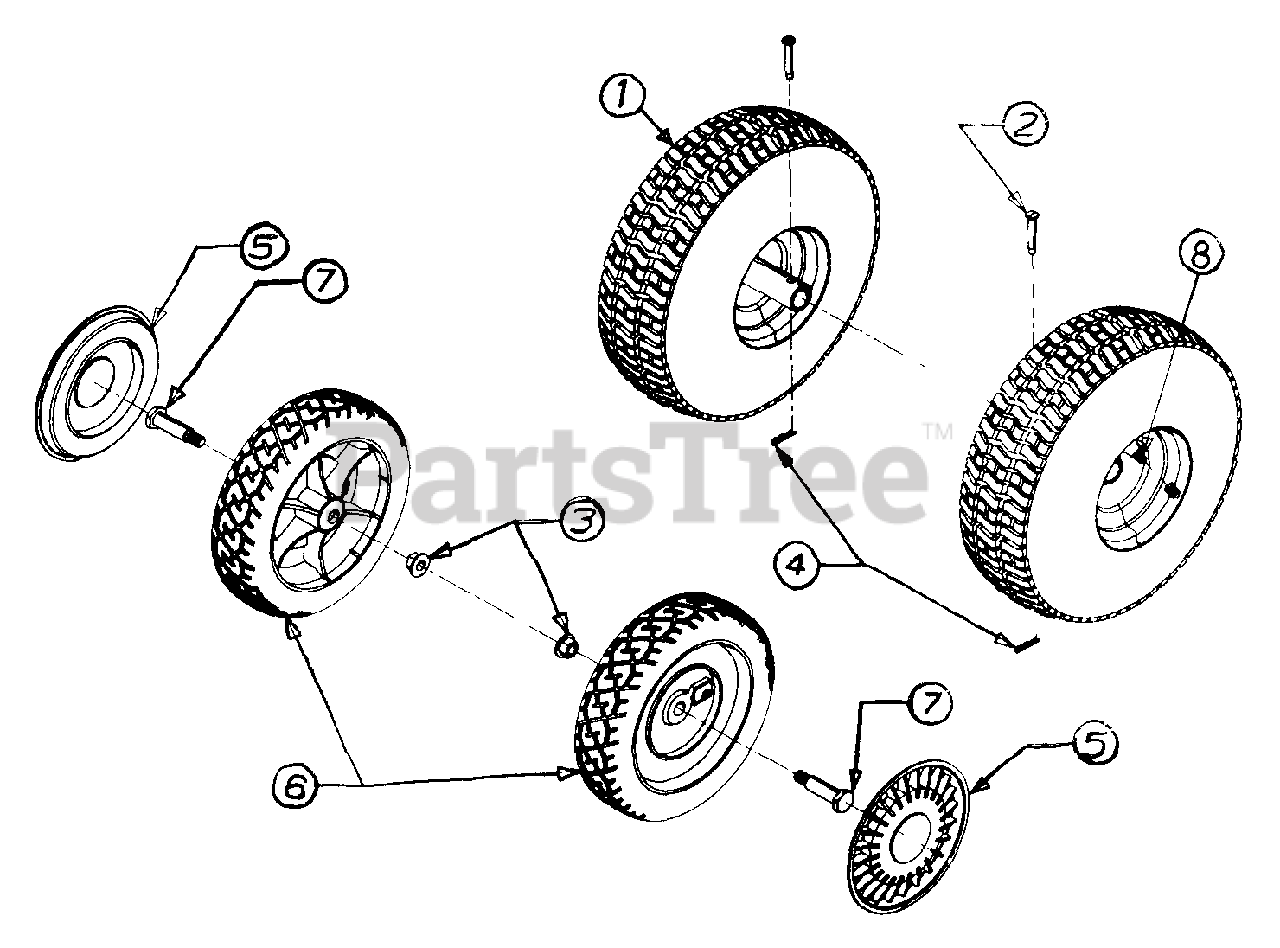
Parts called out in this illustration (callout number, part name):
1	WHEEL ASSY COMPLETE 4" X 10"
2	PIN - CLEVIS
3	NUT - HEX FLANGE
4	PIN - COTTER
5	HUB CAP
6	WHEEL 2" X 8"
7	SCREW - SHOULDER
8	VALVE STEM
